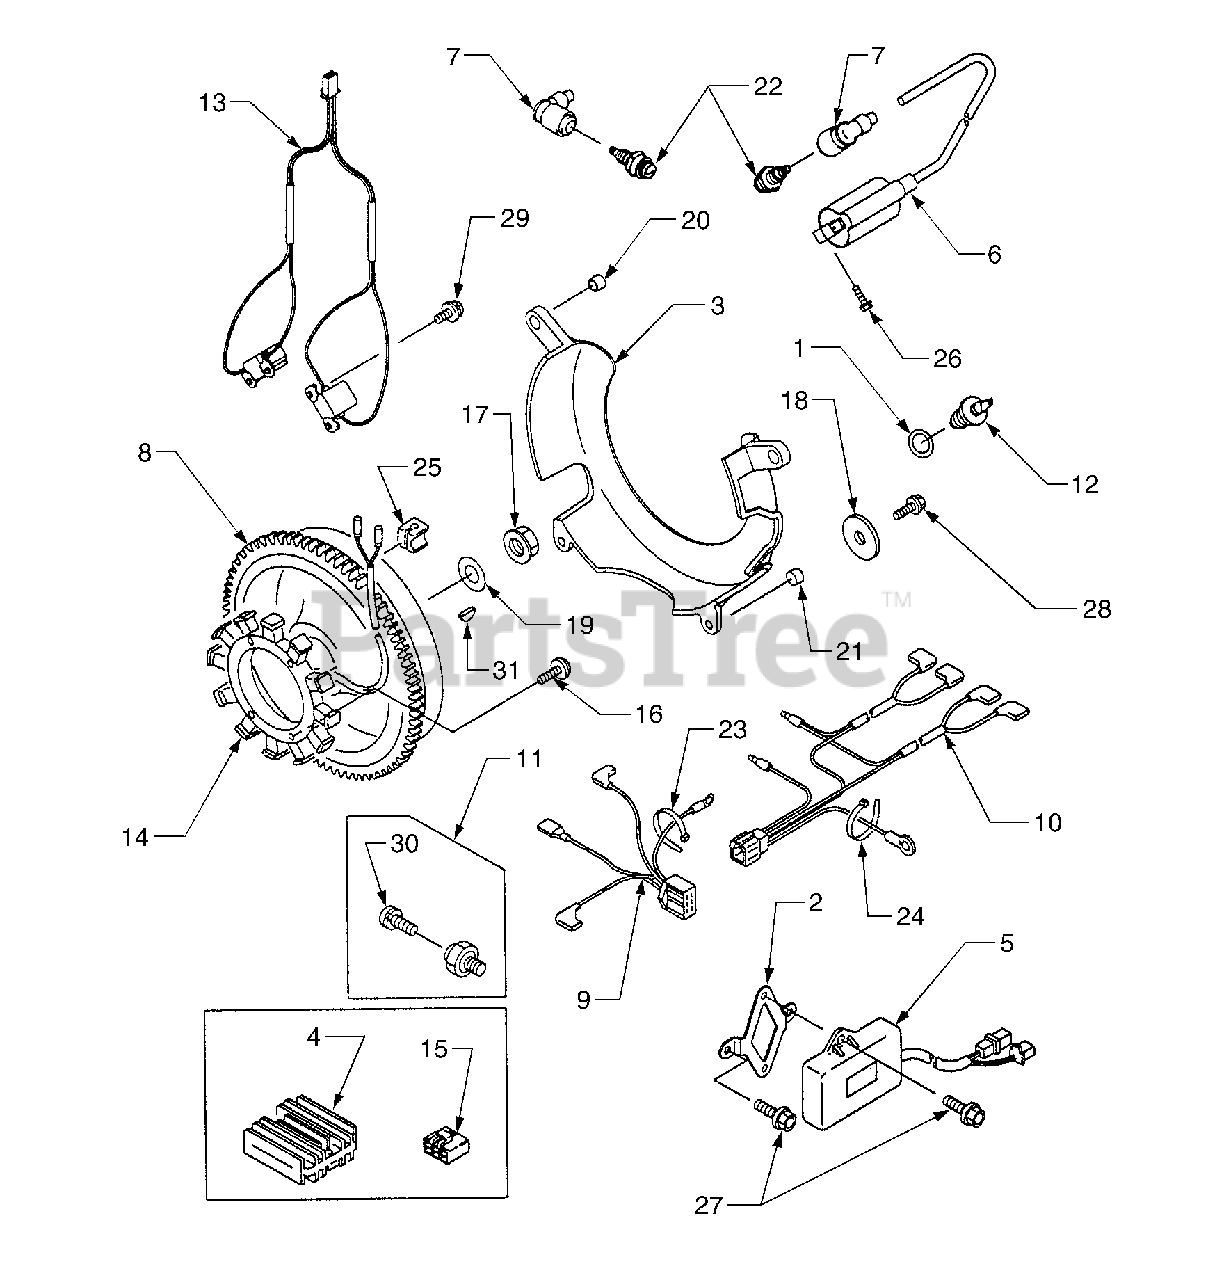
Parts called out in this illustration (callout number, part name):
1	Gasket, Temp. Switch
3	Cover, Flywheel
4	Regulator, Voltage
6	Coil, Ignition
7	Cap, Spark Plug
8	Flywheel Assembly
11	Switch
13	Coil, Pulsing
14	Coil, Charging
20	Collar, 8.3 x 11.5 x 9
21	Collar, 6.2 x 7.8 x 5
22	Plug, Spark
26	Bolt, Flanged, 5 x 20
27	Bolt, Flanged, 6 x 14
28	Bolt, Flanged, 6 x 16
29	Screw, Pan, 4 x 14
30	Screw, Pan, 4 x 6
31	Key, Woodruff
